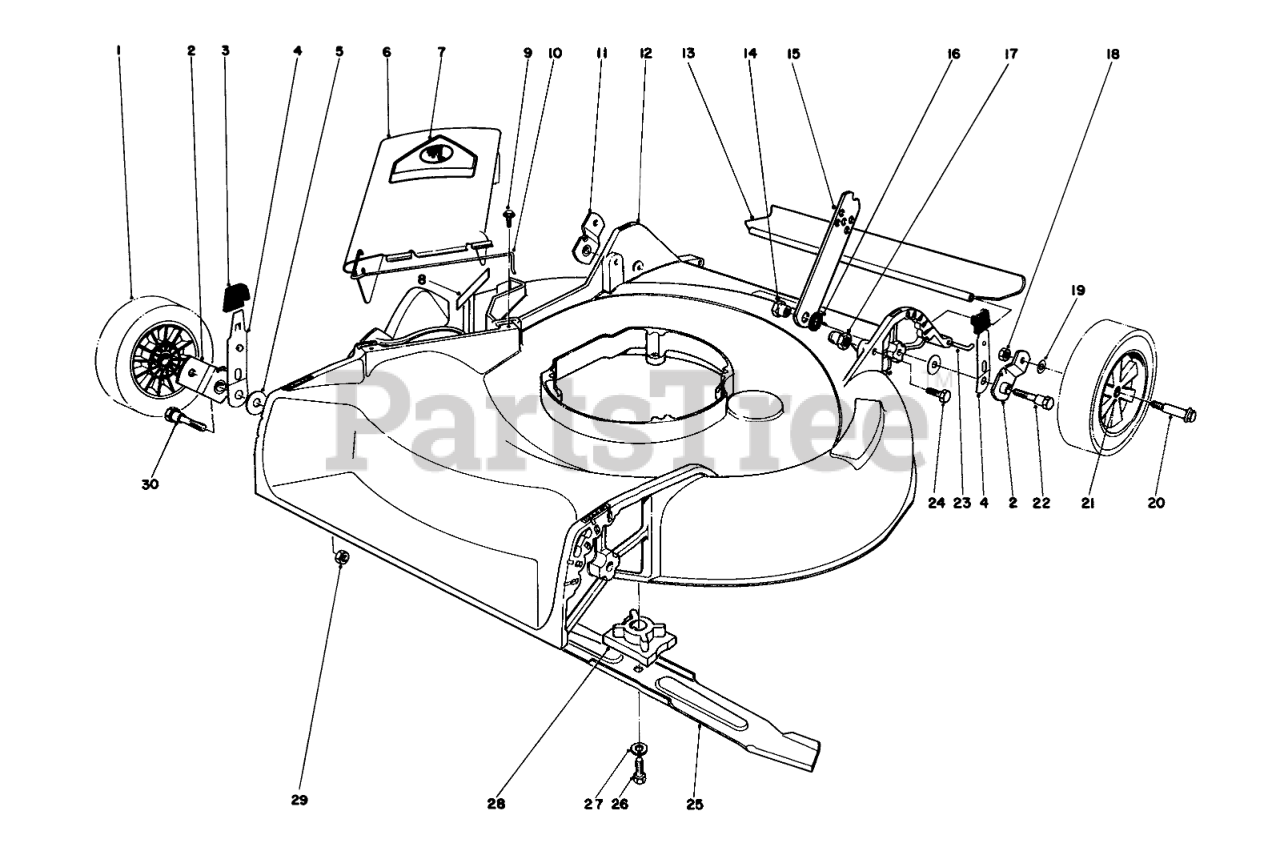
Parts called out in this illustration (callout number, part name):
1	Wheel & Tire Assembly (Incl. Ref. #21)
2	Pivot Arm
3	KNOB-ARM
4	SPRING ARM ASM
5	WASHER-PIVOT
6	Deflector Assembly (Incl. Ref. #7 & 10)
7	DECAL-DANGER
8	Decal
9	SCREW-HWH
10	SPRING HINGE
11	Pivot Arm
12	Housing (Incl. Ref. #8)
13	REAR SAFETY SHIELD 21
14	HANDLE PIVOT NUT
15	HANDLE LATCH
16	SPACER
17	HANDLE PIVOT NUT
18	NUT-LOCK
19	WASHER
20	WHEEL BOLT
21	BUSHING
22	PIVOT SCREW
23	SHIELD ROD
24	SCREW-HH
25	Blade
26	SCREW-HH
27	WASHER-LOCK
28	BLADE RETAINER
29	NUT-LOCK, NI
30	PIVOT SCREW
